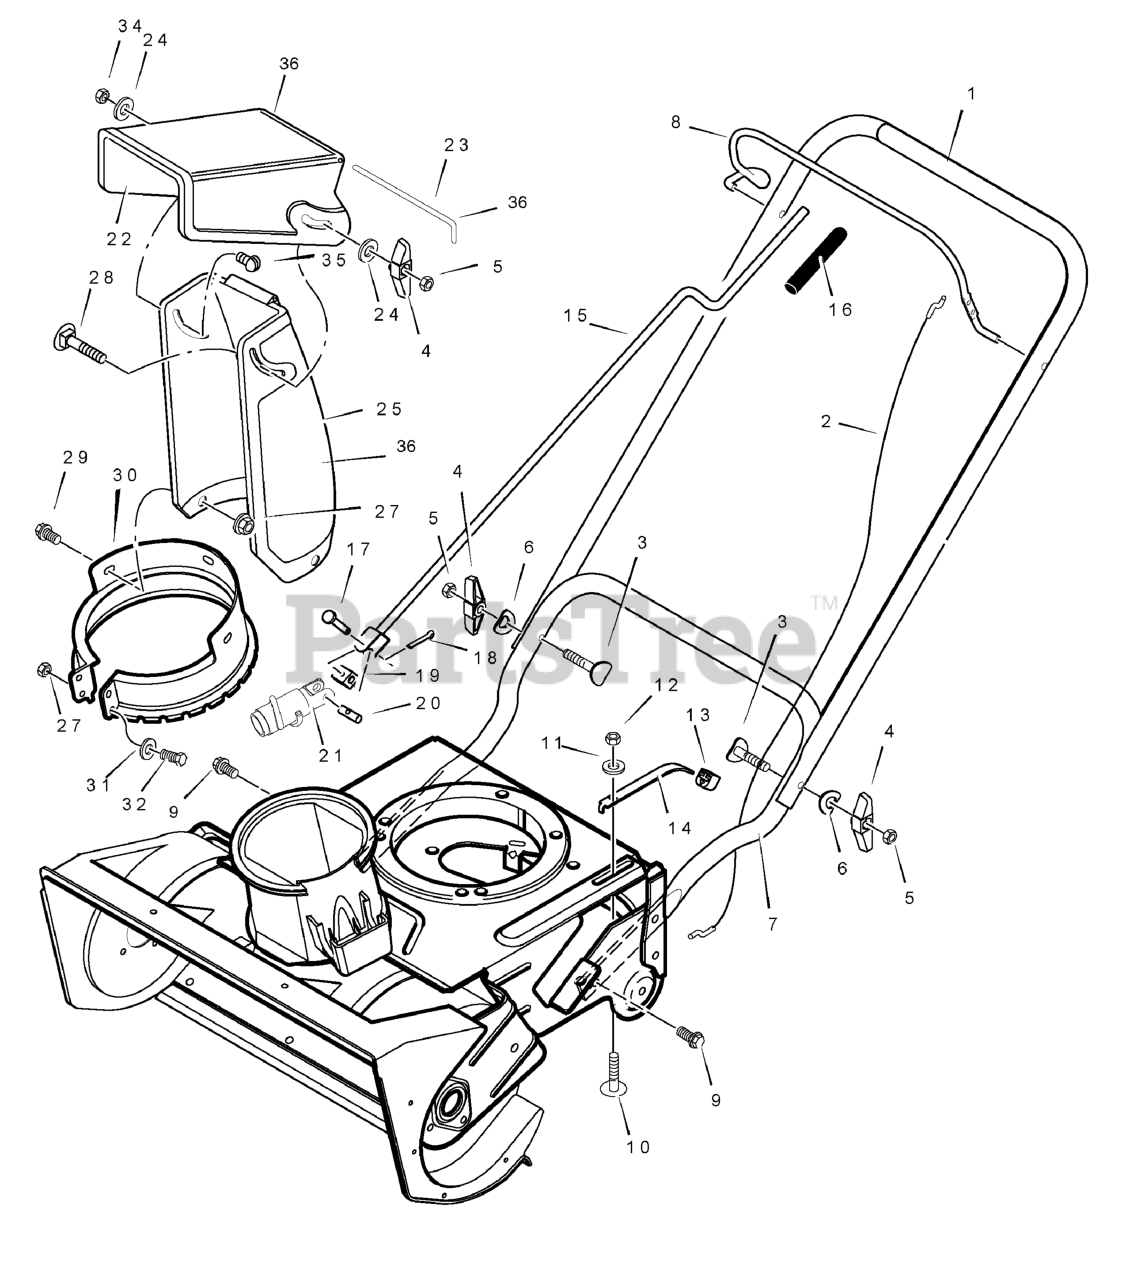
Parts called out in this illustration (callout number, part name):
1	Handle, Upper
2	Cable, Control
3	Bolt, 5/16-18x2.00
4	Knob, Wing
5	Nut
6	Washer, Formed
7	Handle, Lower 21 Inch Snow
8	Lever, Auger Drive Control
9	Screw, 5/16-18 x 0.78
10	Bolt, 1/4-20x.63
11	Flat Washer
12	Nut, 1/4-20
13	Bushing, Tensioner
14	Tensioner, Cable
15	Rod, Crank Upper
16	Grip, Crank Rod
17	Pin, Clevis
18	Pin, Cotter
19	Block, Universal Pivot
20	Pin, Universal Joint
21	Wormgear, Chute Rotate
22	Chute, Upper
23	Wire Form, Hinge
24	Washer, Flat
25	Chute, Discharge Lower
27	Nut, 1/4-20
28	Bolt, 5/16-18x1.25
29	Screw, 1/4-20x.50
30	Ring, Chute
31	Washer, Flat
32	Screw, 1/4-20x.75
35	Screw, 5/16-18 x 0.75
36	CHUTE ASSEMBLY
